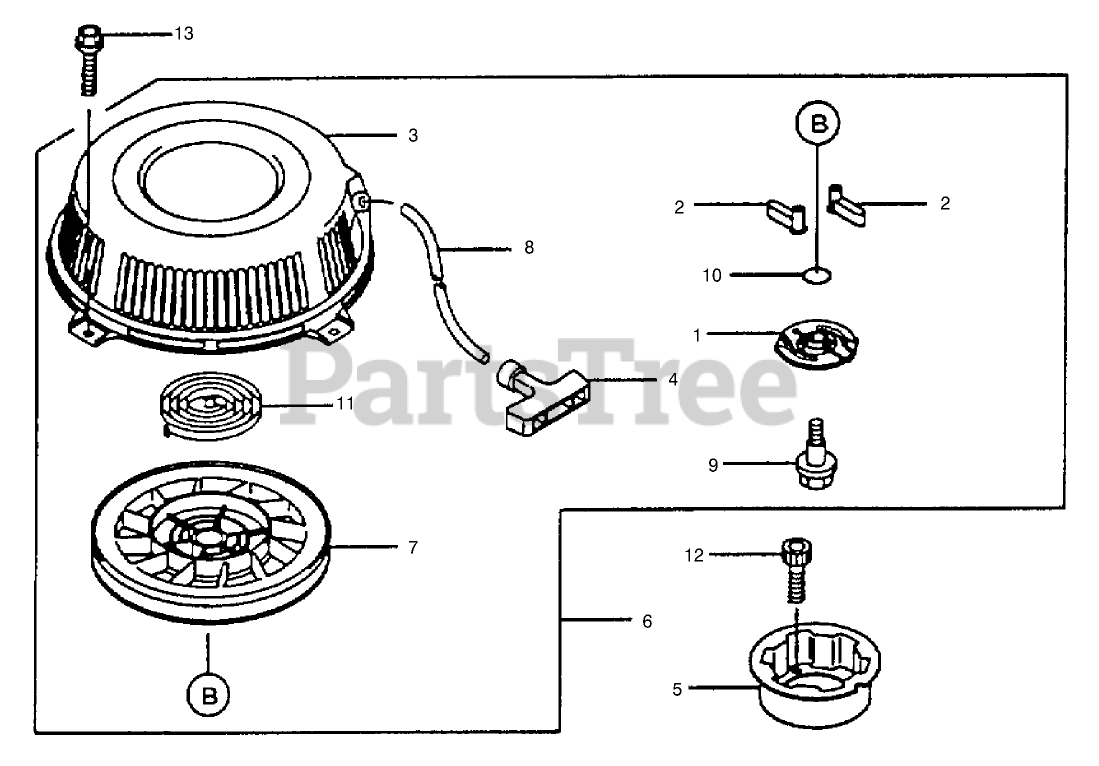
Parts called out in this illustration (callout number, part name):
1	Guide
2	Pawl-Recoil Starter
3	Case-Spring
4	Grip-Recoil Starter
5	Pulley-Starting
6	Starter-Recoil
7	Reel-Recoil Starter
8	Rope
9	Screw
10	Ring-Snap
11	Spring
12	Bolt-Socket
13	BOLT-FLANGED (6X10)
16	Starter-Recoil
